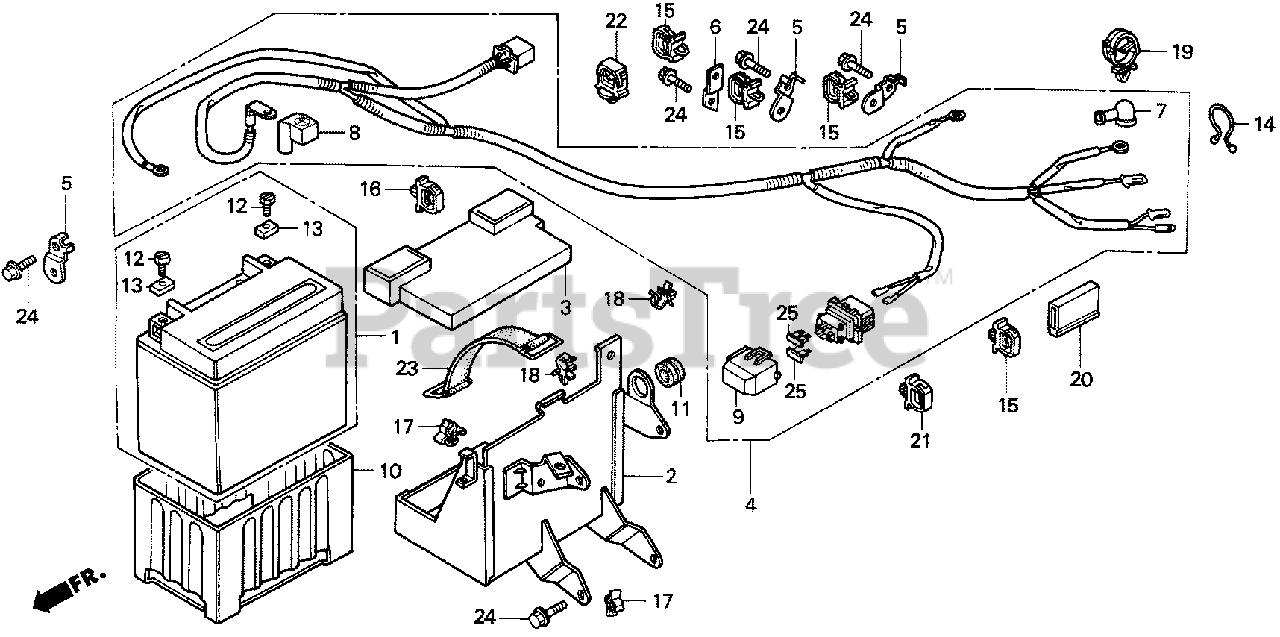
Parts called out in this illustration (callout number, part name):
1	BATTERY (YTH12-12B) (YUASA)
1	BATTERY (YTX12-BS) (YUASA)
2	BOX, BATTERY
3	COVER, BATTERY
4	WIRE HARNESS ASSY.
5	STAY B, CLIP
6	STAY C, CLIP
7	COVER, STARTER MOTOR TERMINAL
8	COVER, BATTERY TERMINAL
9	COVER, FUSE CASE
10	RUBBER, BATTERY
11	RUBBER, BRACKET MOUNTING
12	BOLT, BATTERY TERMINAL
13	NUT, BATTERY TERMINAL
14	CLIP, PURSE LOCK
15	CLIP, WIRE HARNESS (10MM)
16	CLIP, WIRE HARNESS (13MM) (GRAY)
17	CLIP, WIRE HARNESS (6MM) (WHITE)
18	CLIP, HARNESS
19	STRAP, WIRE HARNESS (25MM) (BLACK)
20	TUBE, FASTENER (30)
22	CLIP, HARNESS (7MM)
23	BAND F, BATTERY
24	BOLT, FLANGE (8X14)
25	FUSE, BLADE (5A)
